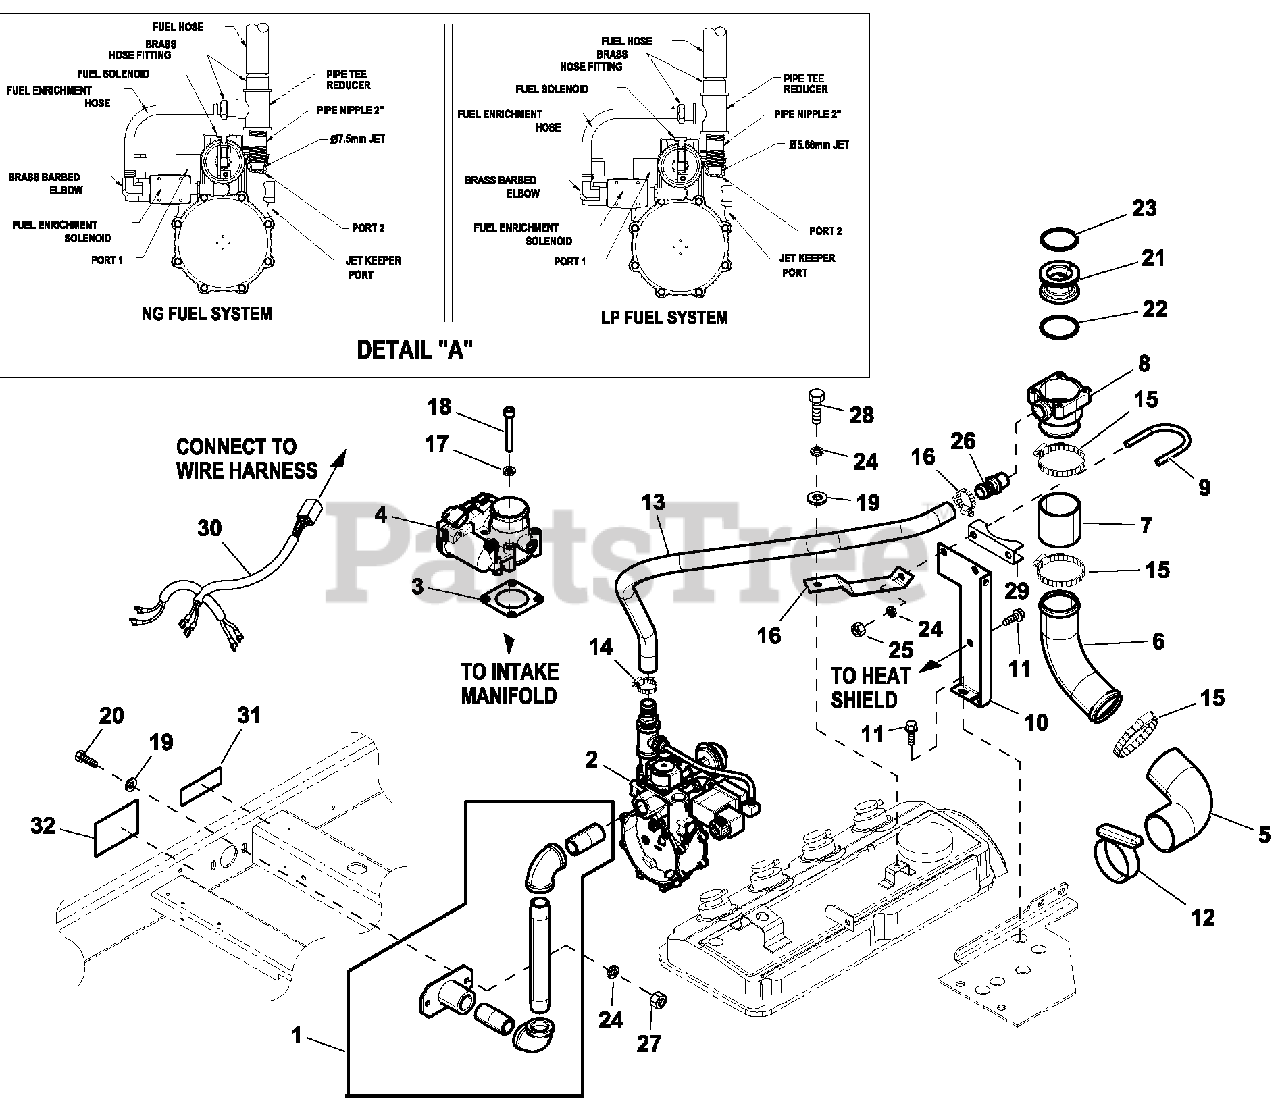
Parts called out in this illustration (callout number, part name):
1	ASSY RGLTR INLET NPT FITTINGS
2	REGULATOR ASSY 2.4L 36KW
3	GASKET, BOSCH 32 & 40
4	ACTUATOR BOSCH 40, GOVERNOR
5	ELBOW RUBBER 90 2" ID
6	INTAKE TUBE 2.4L G2 36KW
7	HOSE COOL 2IN ID 20R4 (3FT)
8	MIXER ACTUATOR
9	BOLT U 5/16-18X 2.09
10	BRACKET INTAKE MANIFOLD
11	SCREW HHTT M6 -1.0 X 12
12	CLAMP CNST TENSION 1.75-2.625
13	HOSE 3/4 ID SAE-30R2 (35"LG)
14	CLAMP HOSE #8 .53-1.00
15	CLAMP HI TORQUE 1.75 - 2.625
16	BRACKET-INTAKE REINFORCEMENT
17	WASHER LOCK M6-1/4
18	SCREW SHC M6-1.0 X 45
19	WASHER FLAT 5/16-M8 ZINC
20	SCREW HHC M8-1.25 X 20 G8.8
21	VENTURI THROTTLE 24MM
22	O-RING 47.625 ID X 2.38 WIDTH
23	O-RING 45.63 ID X 2.62 WIDTH
24	WASHER LOCK M8-5/16
25	NUT HEX 5/16-18 STEEL
26	BARBED STR 1/2N P T X 3/4
27	HEX NUT-METRIC
28	SCREW HHC M8-1.25 X 16 G8.8
29	SADDLE 2 INCH
30	HARNESS FUEL JUMPER SINGLE REG
31	DECAL INLET PRESSURE
32	DECAL FUEL INLET NG
